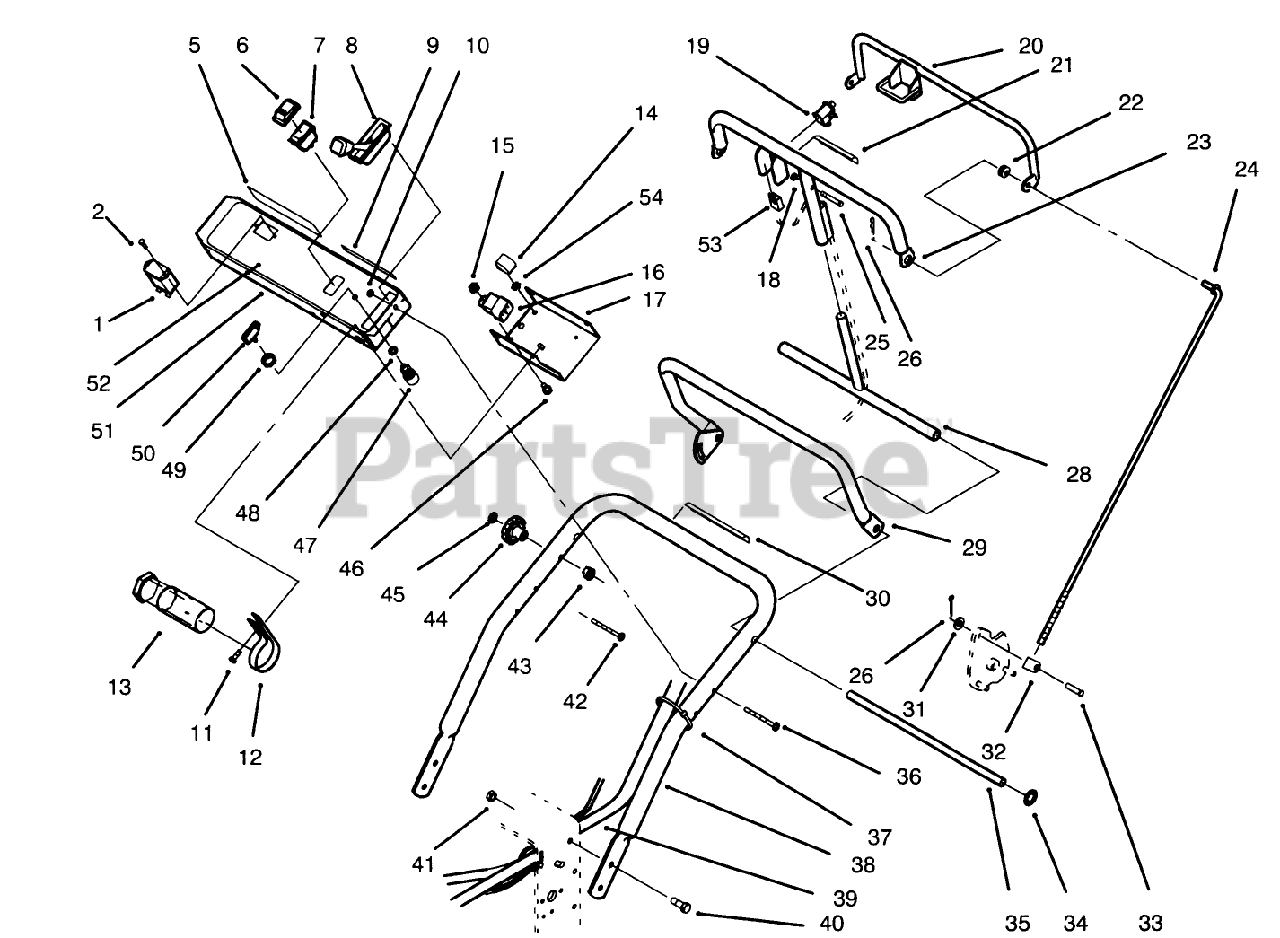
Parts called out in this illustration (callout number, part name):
1	HOURMETER
2	SCREW-HWH
5	DECAL-INSTRUCTION, SAFETY
6	BOOT-SWITCH
7	SWITCH
8	CONTROL-THROTTLE
9	DECAL-INSTRUCTION
10	NUT-LOCK, NI
11	SCREW-SHWH
12	CLAMP-R
13	TUBE-MANUAL
14	Module
15	NUT-LOCK, NI
16	RELAY
17	Panel-Bottom
18	NUT-LOCK, NI
19	SWITCH-BAIL
20	Bail
21	DECAL - CONTROL BAR
22	GROMMET-RUBBER
23	Bar
24	ROD-CONTROL
25	SCREW-SHH
26	PIN-COTTER
28	Pivot Control Assembly
29	REFERENCE HANDLE WA B
30	DECAL-WARNING
31	WASHER-PLAIN
32	FITTING-ROD
33	PIN-CLEVIS
34	NUT-PUSH-ON, CIRCULAR
35	PIVOT ROD
36	SCREW-SHH
37	TIE-CABLE
38	UPPER HANDLE R
39	WIRE HARNESS-14HP HYDRO
40	SCREW-HHF
41	NUT-HF
42	SCREW-CARR
43	SPACER
45	BOLT RETAINER
46	SCREW-HH
47	SWITCH-STARTER
48	SCREW-HHF
49	NUT-HH
50	KEY-IGNITION
51	Panel-Control
52	DECAL - CONTROL PANEL
53	CONNECTOR-BODY
54	WASHER-LOCK/EXT
